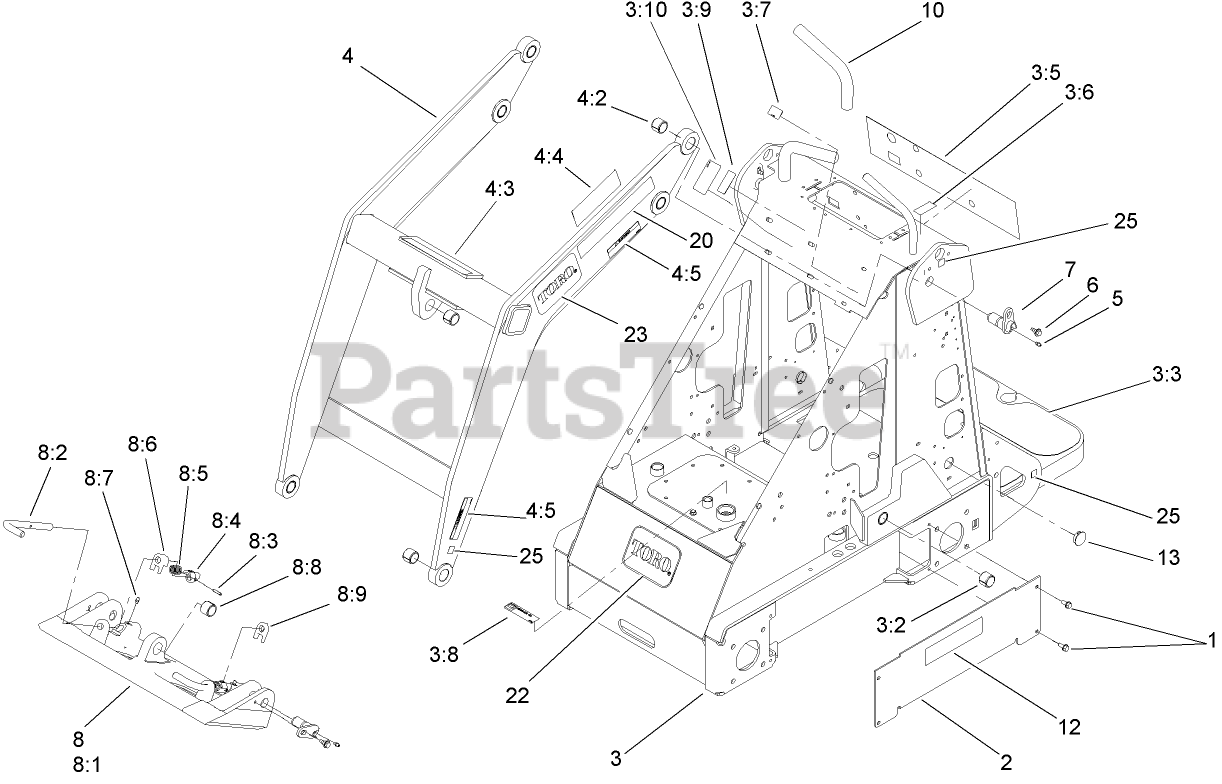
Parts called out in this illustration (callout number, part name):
1	SCREW-HWHTF
2	COVER-HOSE
3	FRAME ASM
3:2	BUSHING-TENSION
3:3	TREAD-FOOT
3:5	DECAL-PANEL, CONTROL
3:6	DECAL-THROTTLE
3:7	DECAL-LIMITER, SPEED
3:8	DECAL-OIL, HYD
3:9	DECAL-SELECTOR
3:10	DECAL-POWER, AUXILIARY
4	LOADER ASM
4:2	BUSHING-TENSION
4:3	DECAL-CAUTION
4:4	DECAL-DANGER
4:5	DECAL-PINCH
5	FITTING-GREASE
6	BOLT-SHOULDER
7	PIN-PIVOT
8	QUICK ATTACH ASM
8:1	MOUNT-ATTACH, QUICK
8:2	PIN-LOCKING
8:3	PIN-GROOVED
8:5	SPRING-COMPRESSION
8:6	STOP-RH
8:7	FITTING-GREASE
8:8	BUSHING-TENSION
8:9	STOP-LH
10	GRIP-CUSHION
13	PLUG-HOLE
20	DECAL
22	DECAL
23	DECAL
25	DECAL-POINT, LIFT
